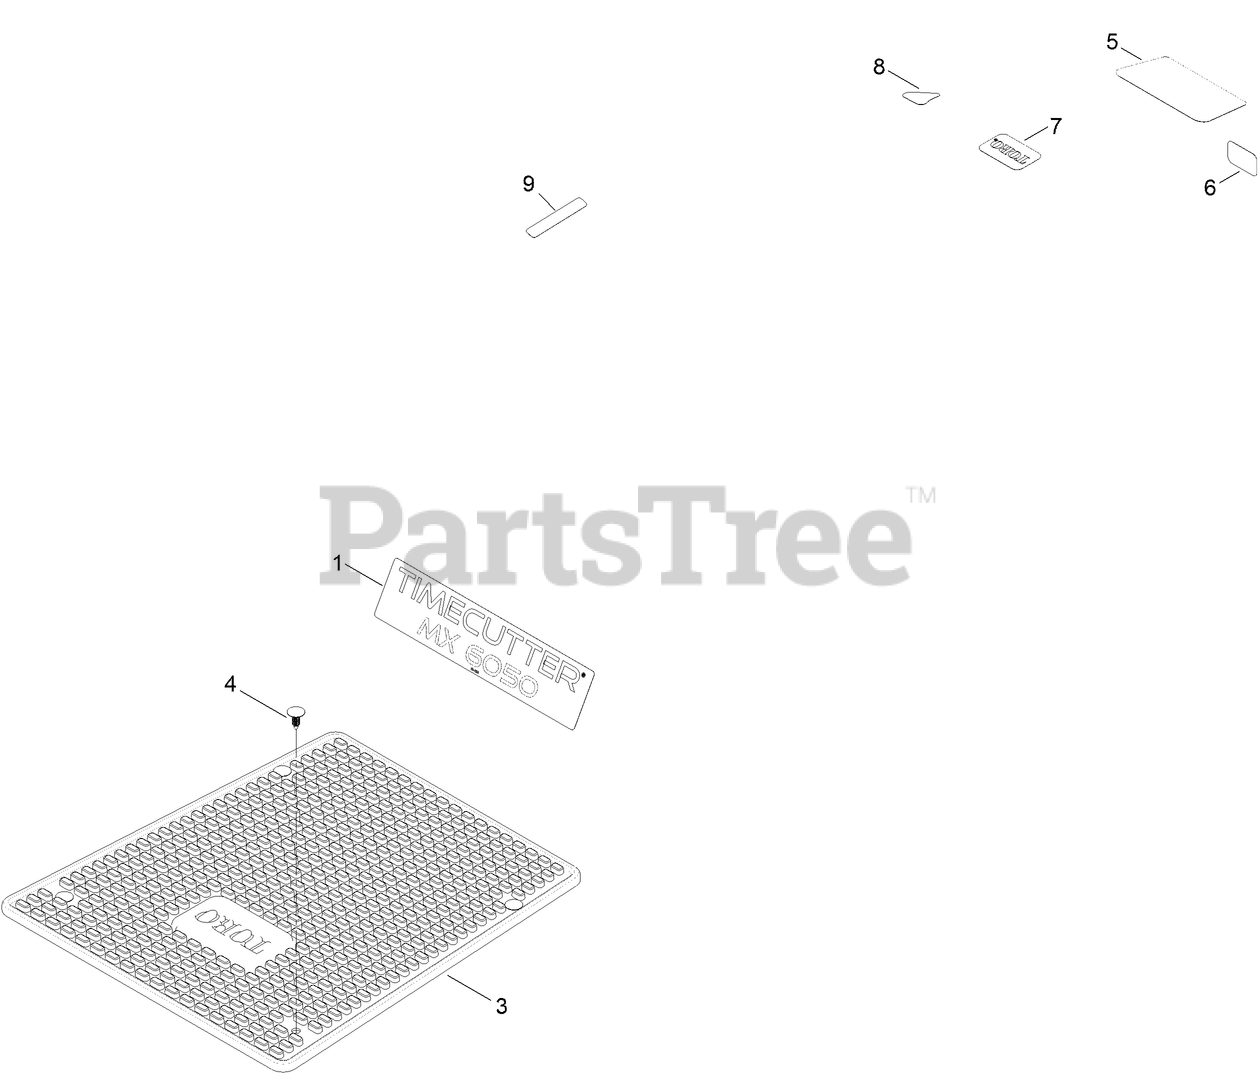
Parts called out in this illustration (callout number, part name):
1	DECAL-TIMECUTTER
3	MAT-FLOOR
4	PLUG-PLASTIC
5	DECAL-ENGINE
6	PLACARD-INTAKE
8	DECAL-DRAIN, OIL
9	DECAL-SHUTDOWN
